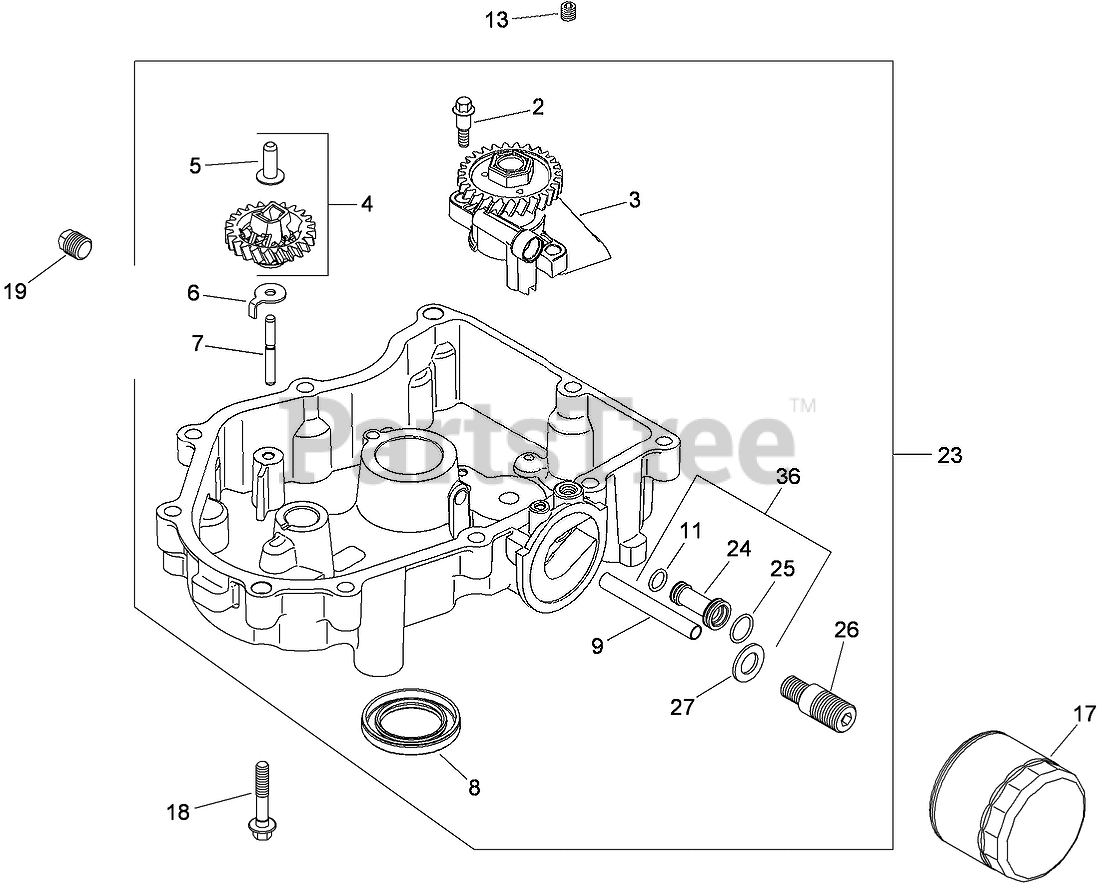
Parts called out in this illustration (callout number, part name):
2	SCREW-SHOULDER, THD FRM (M6x1.0x26.5)
3	OIL PUMP ASM
4	GOVERNOR GEAR W/PIN KIT (INCLUDES 5)
5	PIN-REGULATING, GOVERNOR
6	TAB-LOCKING
7	SHAFT-GEAR, GOVERNOR
8	SEAL-OIL
9	TUBE-FEED, OIL (FILTER TO PAN)
11	O-RING
13	PLUG-PIPE, COUNTERSUNK (1/8)
17	FILTER-OIL
18	SCREW-FLANGE (M8X1.25X45)
19	PLUG-PIPE, SQ HD (3/8)
23	OIL PAN ASM (INCLUDES 2-9, 11 QTY 1], 24-27)
24	TUBE-FEED, OIL
25	O-RING
26	NIPPLE-FILTER, OIL
27	WASHER-FLAT
36	OIL FEED TUBE ASM (INCLUDES 11 QTY 1], 24, 25)
